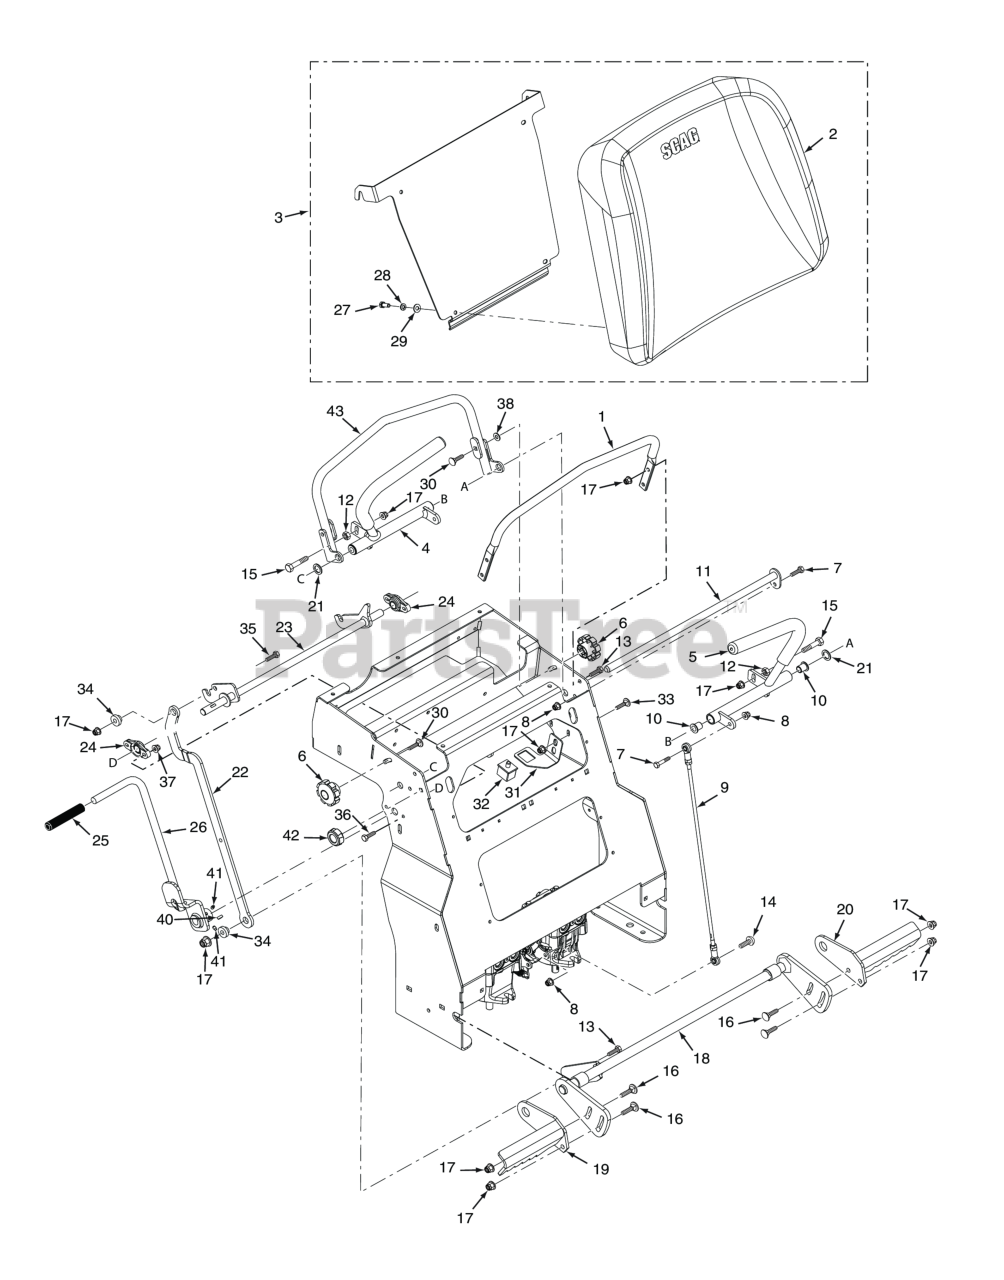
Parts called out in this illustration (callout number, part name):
1	Reference Bar
2	Operator Pad
3	Operator Pad Assy., w/Decal
4	Handlebar Assembly, LH
5	Handlebar Assembly, RH
6	Knob, 5/16 - 18
7	Bolt, Hex 5/16" - .375 x 1.00- Stainless Steel
8	Locknut, 5/16-18 Flg. Elastic Stop - Stainless Steel
9	Linkage Assy., Steering
10	Bearing, .625 ID Plastic
11	Shaft Weldment, Control Arm
12	Nut, 3/8 - 16 - Stainless Steel
13	Bolt, Hex Head 3/8 - 16 x 1.50 - Stainless Steel
14	Hex Head Socket, 5/16-18 x 1" (36)
15	Bolt, Hex 3/8 - 16 x 1.75 - Stainless Steel
16	Bolt, Carriage 3/8 - 16 x 1.25 - Stainless Steel
17	Nut, Flange Elastic Stop 3/8 - 16 - Stainless Steel
18	Bellcrank Weldment, Brake
19	BRAKE PADDLE WLMT, LH
20	Brake Paddle Weldment, RH
21	Washer, Flat 5/8 - .687 x 1.00 x .078 - Stainless Steel
22	Link, Brake Engage
23	Lock Weldment, Neutral
24	Bearing
25	GRIP, PARKING BRAKE
26	Brake Lever Assembly
27	Bolt, Hex 5/16 - 18 x .75 - Stainless Steel
28	Washer, Lock 5/16 Spring - Stainless Steel
29	Washer, Flat 5/16 - .349 x .750 x .050 - Stainless Steel
30	Bolt, Carriage 5/16 - 18 x 1" - - Stainless Steel
31	Mounting Bracket, Brake Switch
32	Switch, Double Pole - Plunger
33	Bolt, Carriage 3/8-16 x 1.0 - Stainless Steel
34	BUSHING, BRONZE - .376 ID X .627 OD
35	Cap Screw, 3/8 - 16 x 1.25 Hex Socket - Stainless Steel
36	Bolt, Hex 1/4 - 20 x 1.25 - Stainless Steel
37	Locknut, 1/4 - 20 Flg. Elastic Stop - Stainless Steel
38	Washer, Flat 5/16 - .349 x .750 x .050 - Stainless Steel
39	Nut, Push On - Stainless Steel
40	KEY, WOODRUFF #61, 3/16 X 5/8
41	Set Screw, 1/4 - 20 x .25 - Stainless Steel
42	Knob, 5/16-18
43	Weldment, Reference Bar
